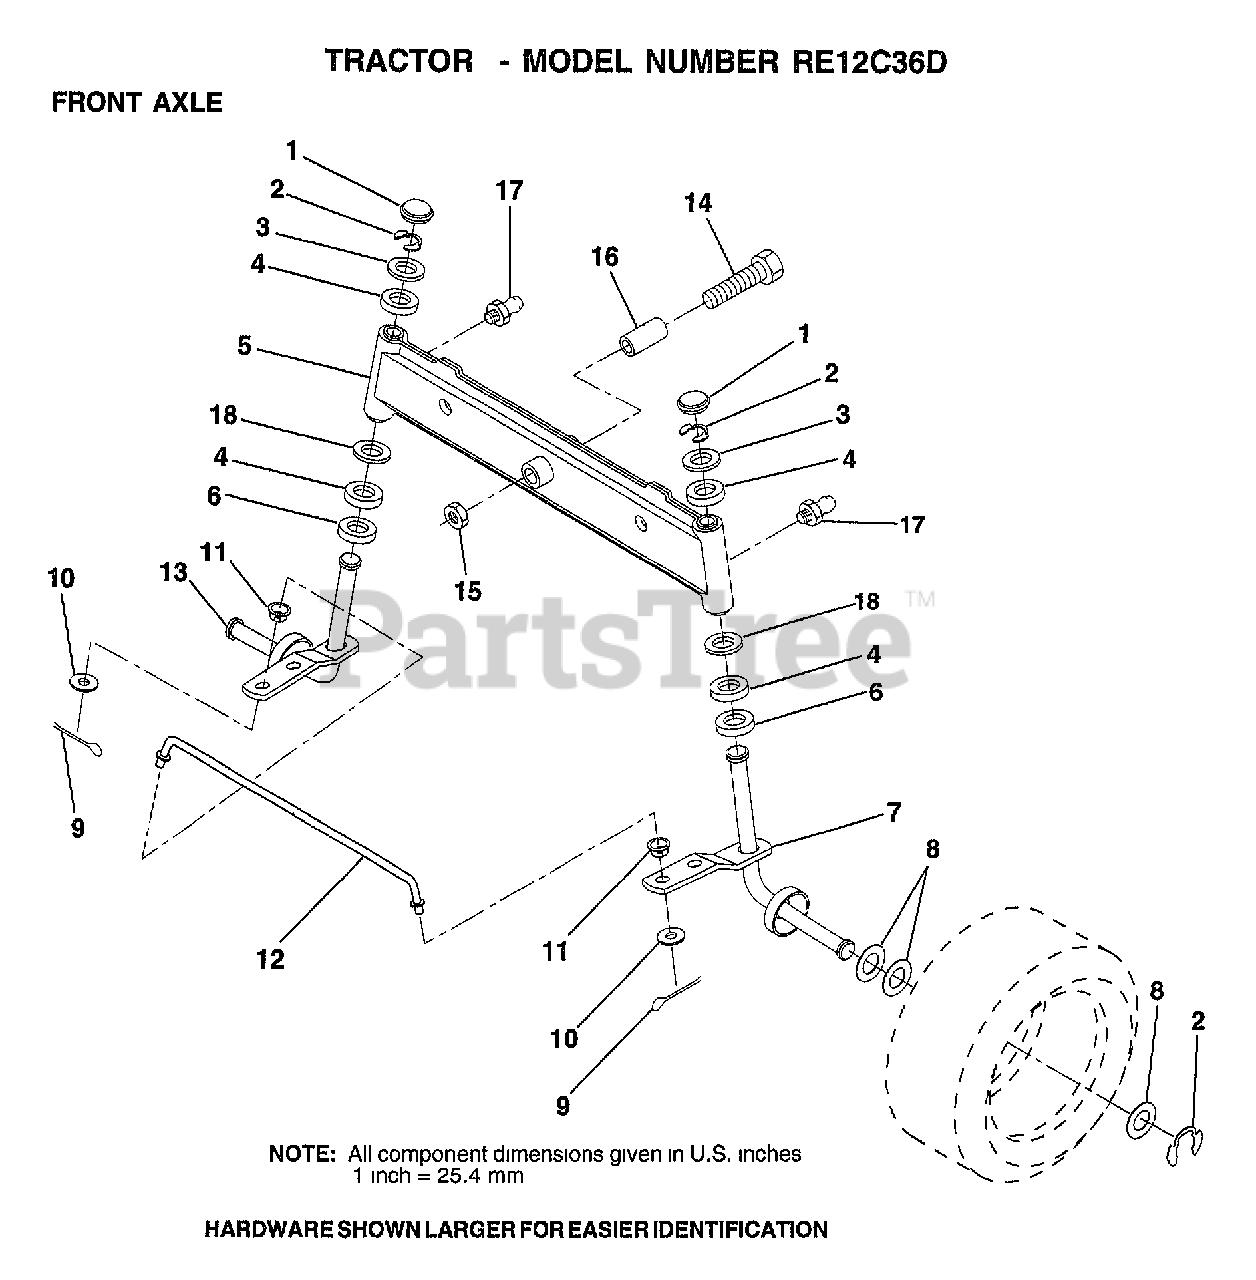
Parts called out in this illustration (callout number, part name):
1	CAP
2	RING
3	WASHER
4	COL. SRTG. BEAR.
5	AXLE ASM FRONT
6	WASHER .T
7	SPINDLE.ASSY.RH
8	WASHER
9	COTTER PIN
10	WASHER
11	BUSHING.DRAGLINK
12	TIE ROD
13	SPINDLE.ASSY.LH
14	BOLT HEX 5/8-11
15	"NUT-LOC,FLANGE LT"
16	BEARING
17	ZERK M
18	WASHER
